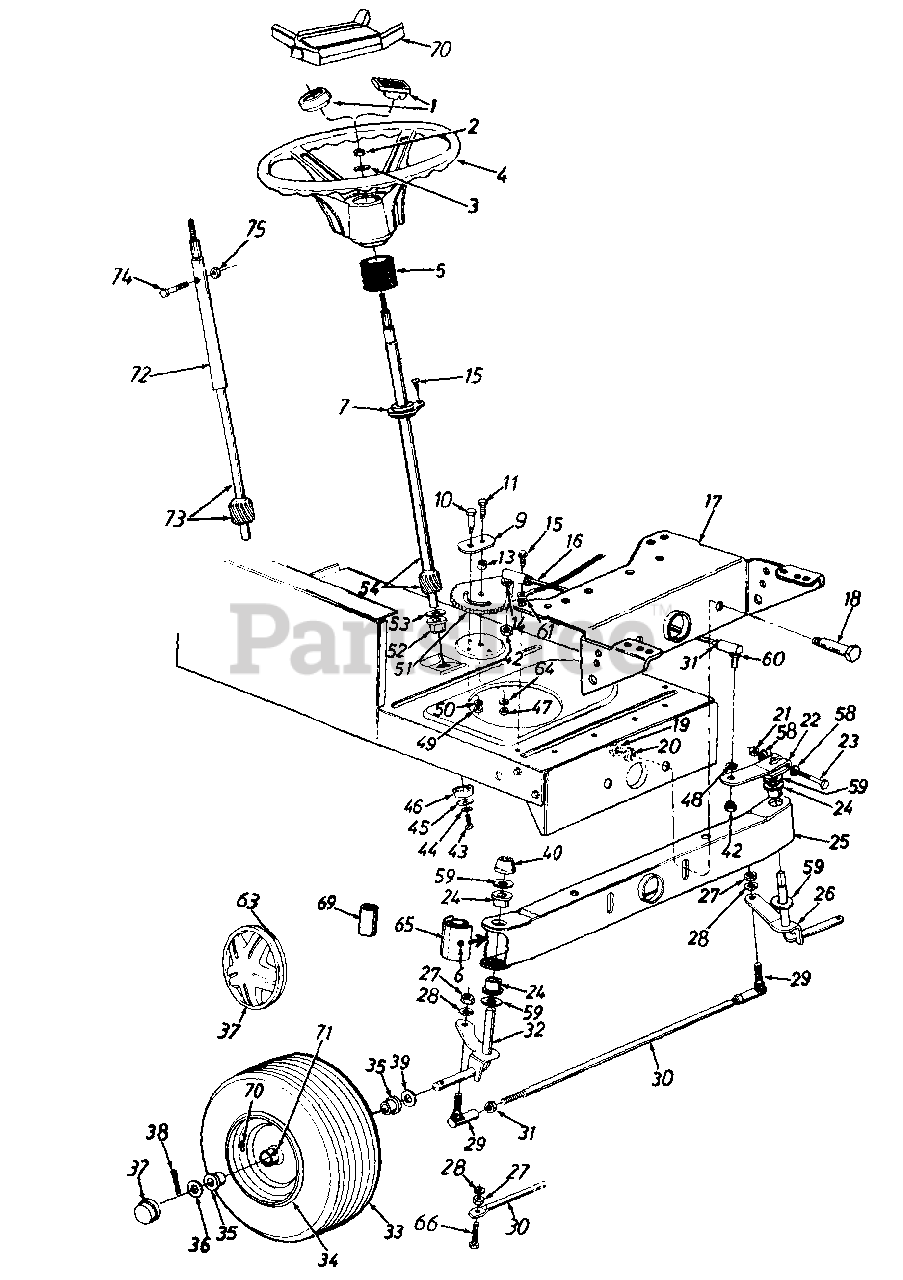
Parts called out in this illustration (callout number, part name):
1	Steering Wheel Cap
2	Hex L-Nut 5/16-24 Thd.
3	Belleville Wash. .345" 1.D.
4	Steering Wheel (3 Spoke)
5	Steering Bellow - 4.5"
7	Flange Bearing .628" I.D. x 1.36 O.D.
9	Retainer Plate
10	Shoulder Bolt .437" Dia. x .35 Lg. 5/16-18 Thd.
11	Hex Bolt 3/8-24 x 1.0" Lg. (Gr. 5)
13	Spacer .380" I.D. x .625" O.D. x .227
14	L-Wash. 3/8" I.D. (H.D.)
15	Hex Wash. Hd. Self-Tap Scr.
16	Steering Drag Link
18	Shoulder Bolt .498" Dia. x 2.04 Lg. 3/8-16 Thd.
19	Hex Nut 3/8-16 Thd."
20	L-Wash. 3/8" I.D.
21	Hex L-Nut 5/16-24 Thd.
22	Steering Arm Front Axle
23	Hex Bolt 5/16-24 x 2.00" Lg. (Grade 5)
24	Hex Flg. Brg. .632 I.D.
26	Front Axle Ass'y. - L.H.
27	Hex Nut 3/8-24 Thd.
28	L-Wash. 3/8" I.D.
29	Ball Joint 3/8-24 Thd.
30	Tie Rod (Adjustable)
31	Hex Jam Nut 3/8-24 Thd.
32	Front Axle Ass'y. - R.H.
33	Wheel Ass'y. Comp.
34	Front Wheel Rim Only
35	Bearing
36	Fl-Wash. .635 I.D. x 1.59" O.D.
37	Front Wheel Hub Cap
38	Cotter Pin 1/8" Dia. x 1.25"
39	Fl-Wash. .640" I.D. x 1.24" O.D.
40	Push Cap 5/8" Dia. Rod
42	Hex Jam Nut 3/8-24 Thd.
43	Hex L-Bolt 5/16-18 x .62"
44	L-Wash. 5/16" I.D.
45	Fl-Wash. .33" I.D. x 3.25" O.D.
46	Spacer (Plastic)
47	Hex Cent. L-Nut 3/8-24 Thd.
48	L-Wash. 3/8" I.D.
49	Hex Cent. L-Nut 5/16-18 Thd
50	L-Wash. 5/16" I.D.
51	Steering Gear Segment
52	Hex Flg. Brg..634 I.D.
53	Fl-Wash. (Hardened)
54	Steering Shaft
58	Wave-Wash. .32" I.D. x .62" O.D.
59	Fl-Wash. (Hardened)
60	Drag Link Ball Joint 3/8-24 Thd.
61	Ext. L-Wash. 5/16" I.D.
63	Spring Clip
64	Bell-Wash. .39" I.D. x 1.38" O.D.
65	Pivot Bar End Cap
66	Hex Bolt 3/8-24 x 1.5" Lg. (Gr. 5)
69	Plastic Tube 1.54" Lg.
70	Steering Wheel Insert
72	Upper Steering Shaft
73	Lower Steering Shaft
74	Hex Bolt 1/4-20 x 1.25" Lg.
75	Hex L-Nut 1/4-20 Thd.
